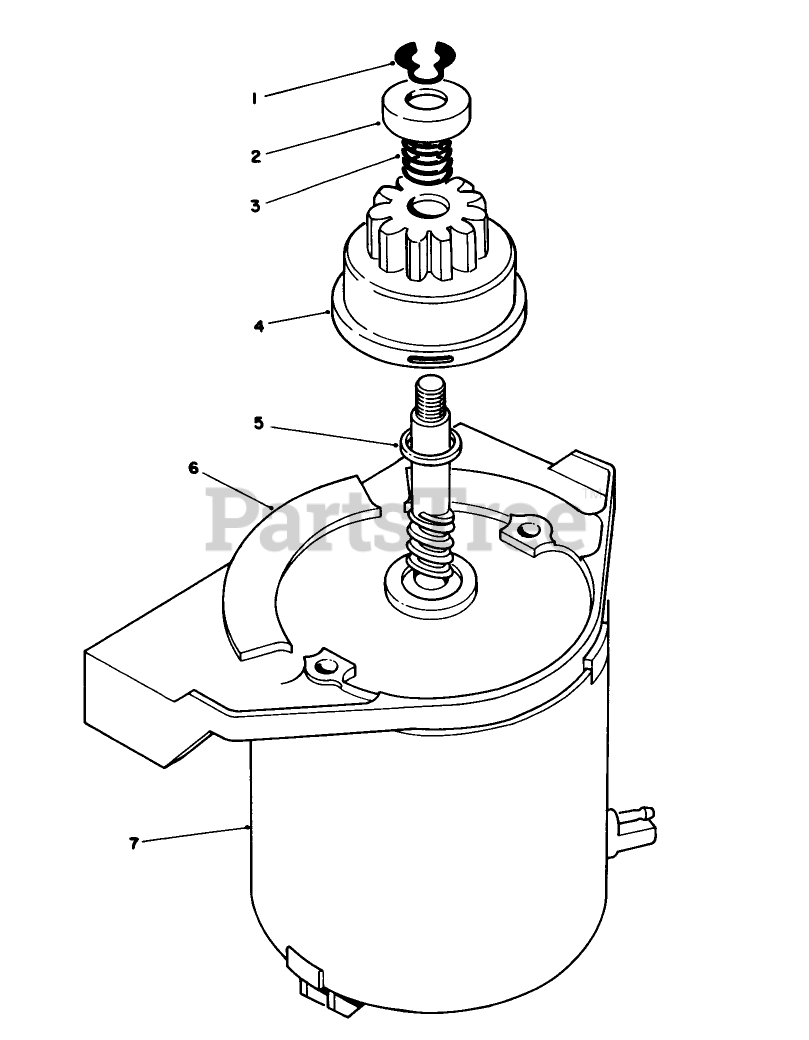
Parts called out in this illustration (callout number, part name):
1	RING-RETAINING
2	PINION STOP
3	COMPRESSION SPRING
4	PINION ASM
5	SPACER
6	END FRAME ASSY, MOTOR
7	STARTER MOTOR ASM
